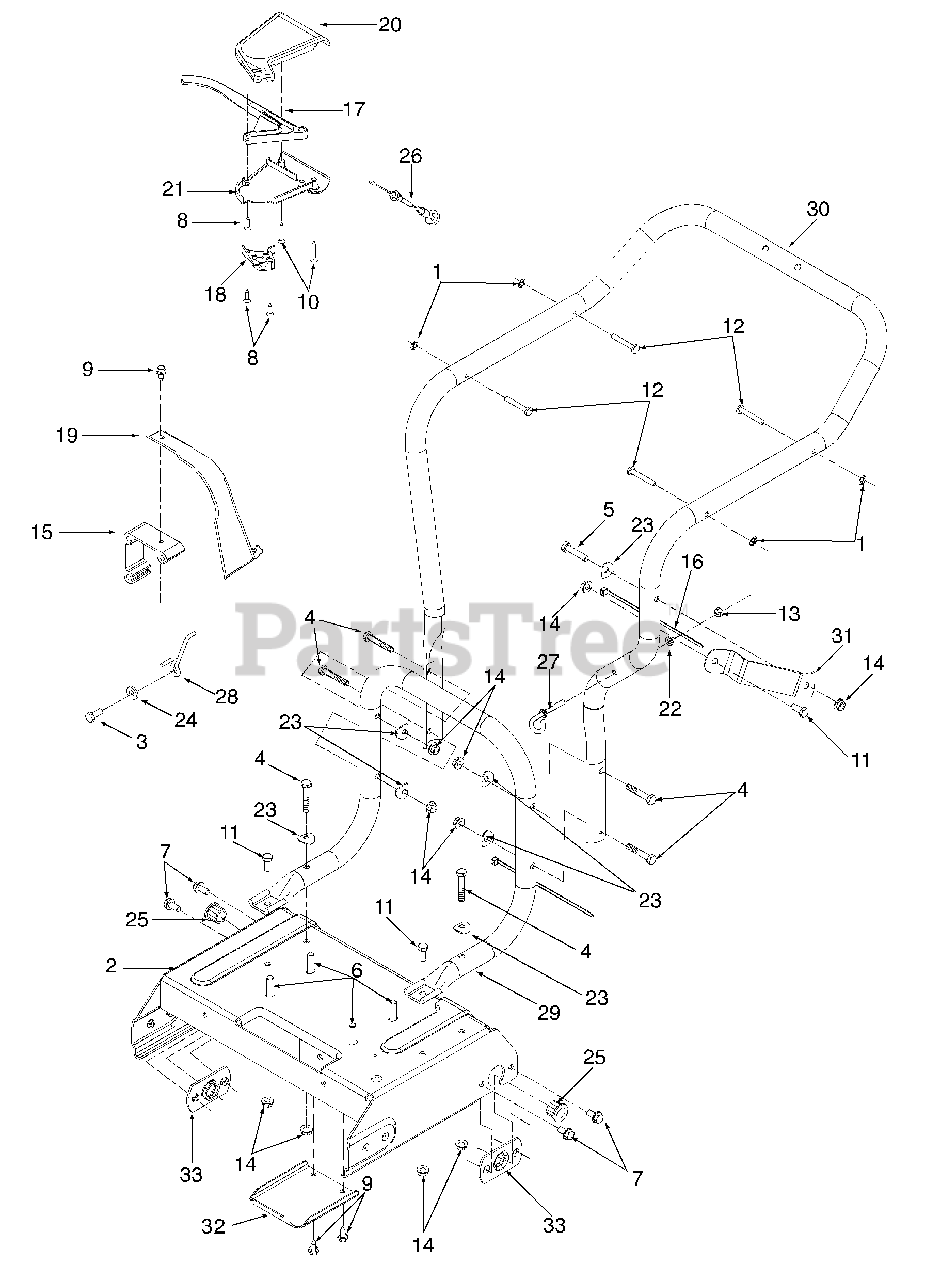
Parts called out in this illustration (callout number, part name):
1	Nut, Push, .25
2	Frame Assembly
3	Screw, Hex Cap, 5/16-24 x .75 GR5
4	Screw, Hex Cap, 5/16-18 x 1.75
5	Screw, Hex Cap, 5/16-18 x 1.5
6	Screw, Hex Wash Hd Tapp, 3/8-16 x 1.25
7	Screw, Hex Wash Hd Tapp, 5/16-18 x .62
8	Screw, Phil Cntrsnk, #10-12 x .75
9	Screw, Hex Wash Hd, 1/4-14 x .62
10	Screw, Phil Cntrsnk, #10-16 x 1.25
11	Screw, Hex Cap, 5/15-18 x .75 GR5
12	Pin, Stud, .250 x 1.75
13	Nut, Hex, 1/4-28
14	Nut, Hex Flange Lock, 5/16-18 GR5
15	Adapter, Engine Mtg
16	Cable Tie
17	Lever, Drive Control
18	Cap, Cable Mtg
19	Belt Cover
20	Upper Clutch Cover
21	Lower Clutch Cover
22	Washer, Lock, 1/4
23	Saddle Washer, .320 x .93
24	Washer, Flat, .344 x .75 x .12
25	Bearing, Flange, .631 ID x .72 OD
26	Cable, Clutch, 56.0
27	Eye Bolt
28	Belt Keeper
29	Handle, Lower
30	Handle, Upper
31	Bracket, Chute Stabilizing
32	Transmission Cover
